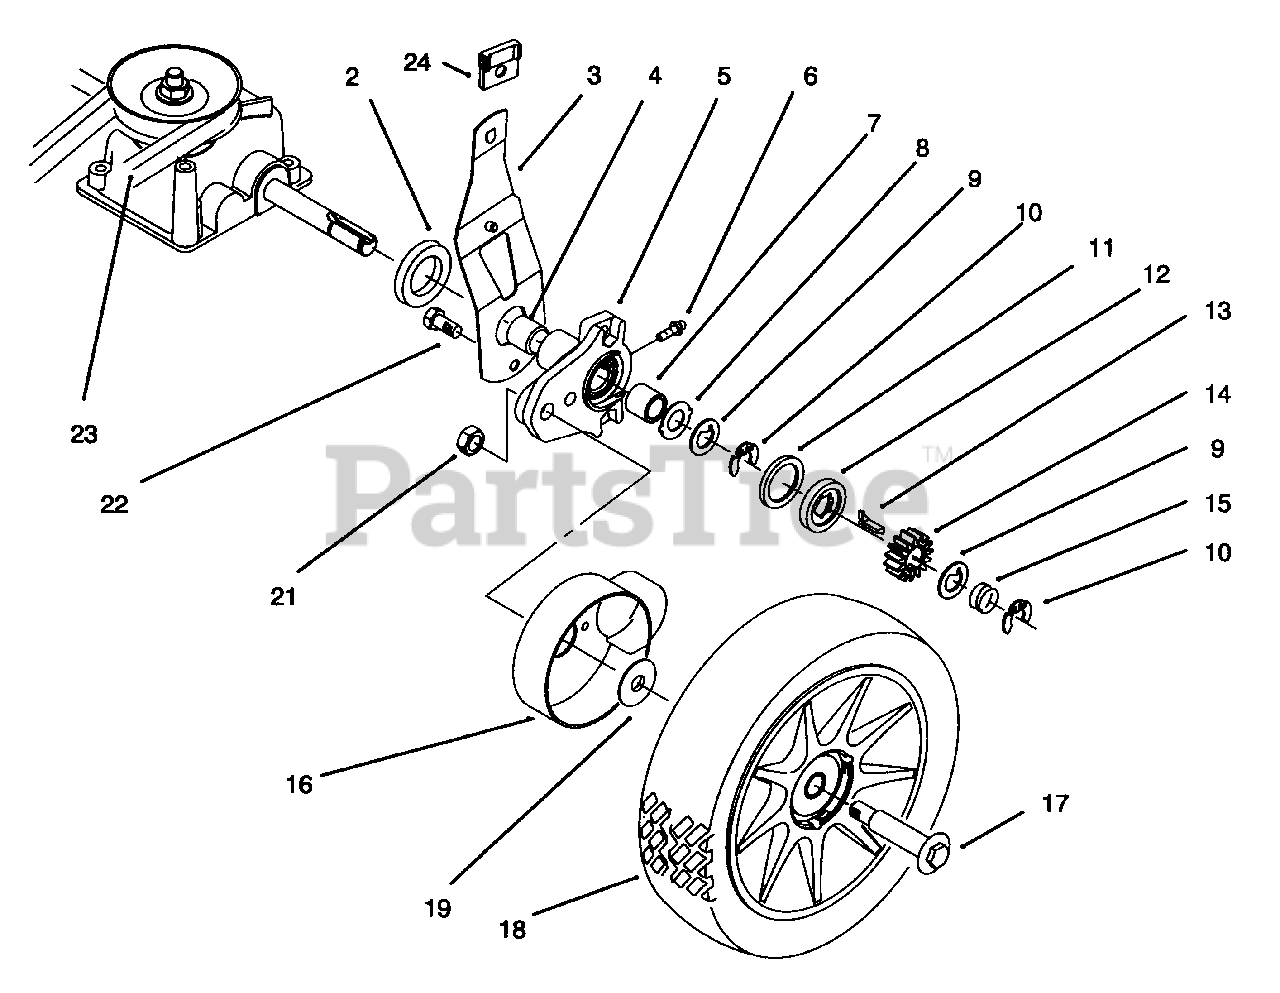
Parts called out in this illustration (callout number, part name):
2	Spacer-Axle Shaft
3	Spring Arm Ass'y
5	Pivot Arm Ass'y-Rear
6	Fitting-Grease (Ref.)
8	Washer-Thrust Pivot Arm
9	Washer-Thrust, Keyed
10	Ring-Klip
11	Ring-Friction
12	Washer-Clutch, Plastic
13	Key-Rocking L.H.
14	Gear-Pinion
15	Spring-Compression
16	Cover Wheel
17	Bolt-Wheel
18	Wheel Ass'y-8"
19	Washer-Stepped
23	"V" Belt
